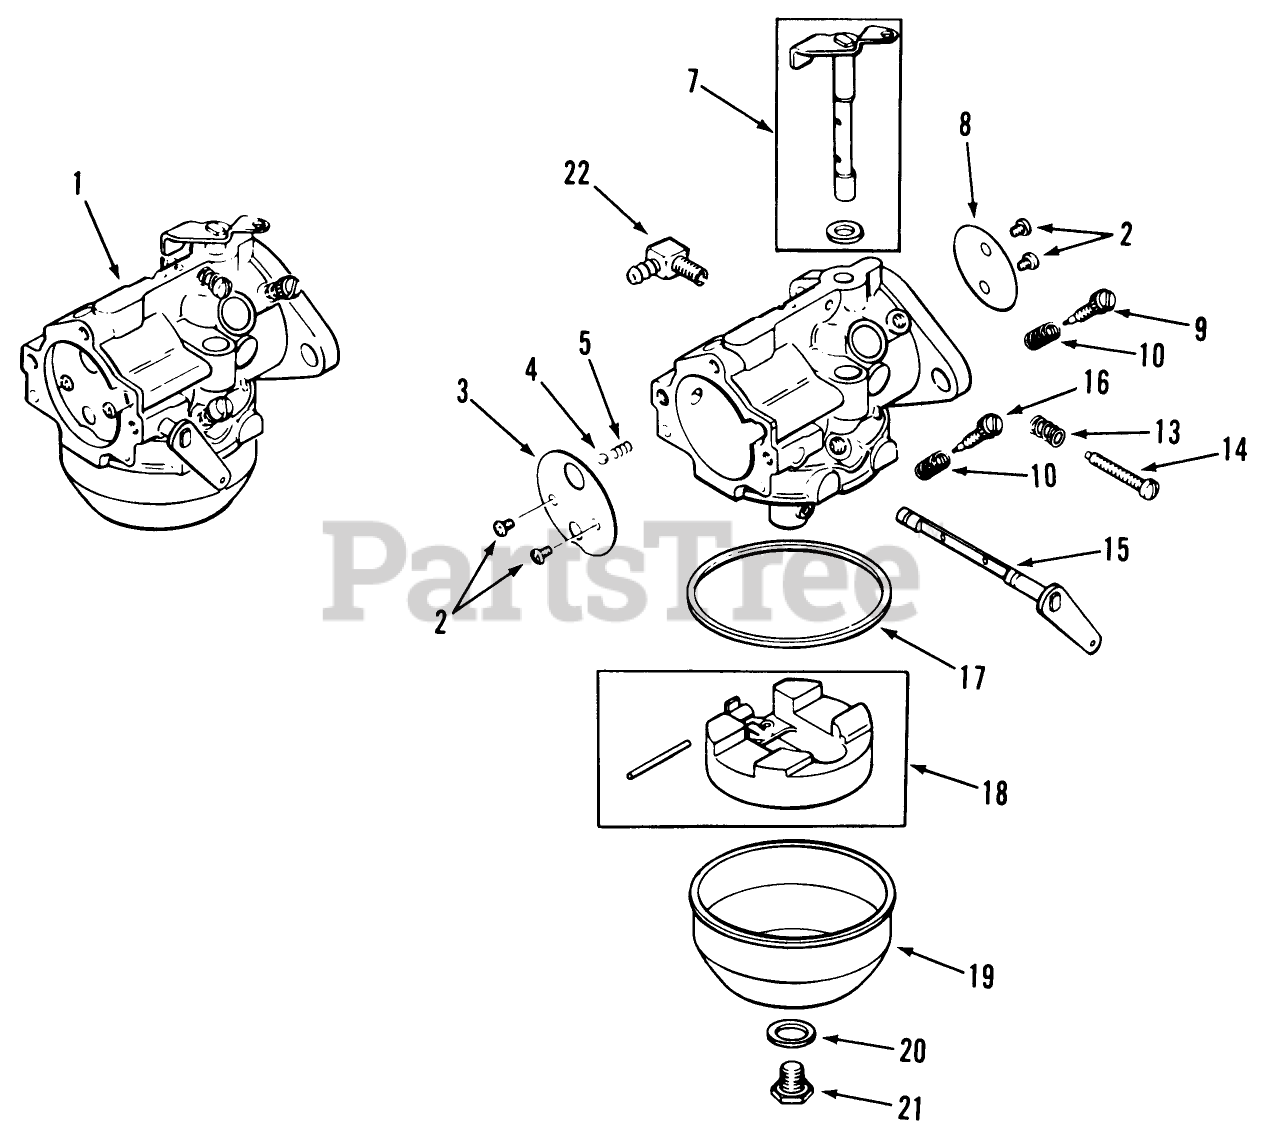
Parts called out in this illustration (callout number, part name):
1	KOHLER 47-853-20
2	KOHLER 25-086-27
3	KOHLER 47-146-08
4	KOHLER 25-194-01
5	KOHLER 25-089-03
7	KOHLER 457-144-21
8	KOHLER 25-146-02
9	KOHLER 25-368-01
10	KOHLER 25-089-02
13	KOHLER 25-089-04
14	KOHLER 25-086-26
15	KOHLER 47-090-38
16	Needle Main
17	KOHLER 25-041-04
18	KOHLER 25-757-09
19	KOHLER 25-104-01
20	KOHLER 25-041-03
21	KOHLER 25-100-05
